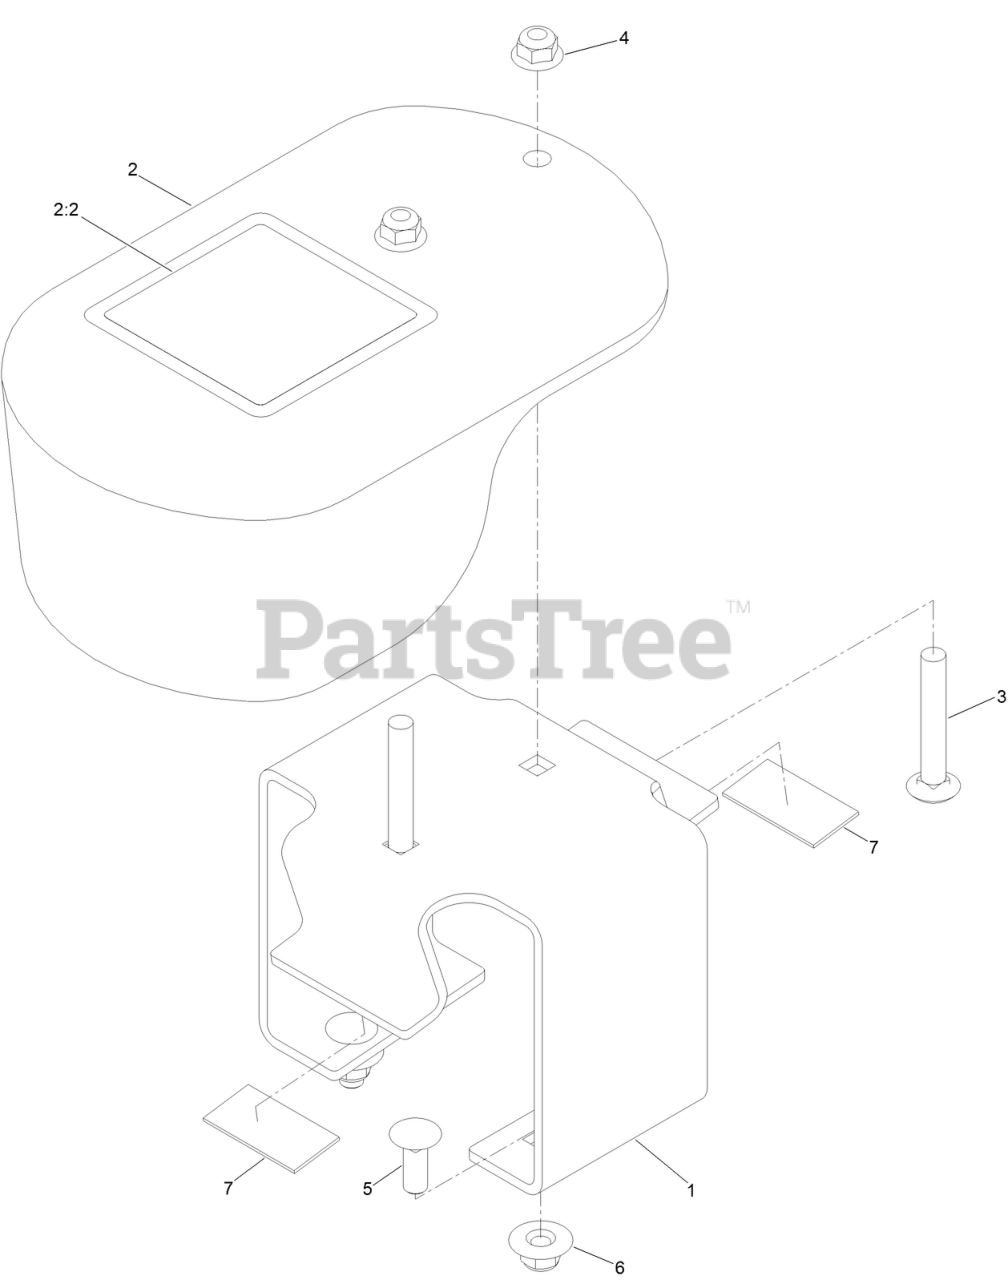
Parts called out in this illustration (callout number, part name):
1	BRACKET-RH CASTER
2	WEIGHT WITH DECAL ASM
2:2	DECAL-WARNING, TRACTION
3	SCREW-CARR
4	NUT-HF, NI
5	SCREW-CARR
6	NUT-FLANGE, NI
7	PAD-RUBBER
